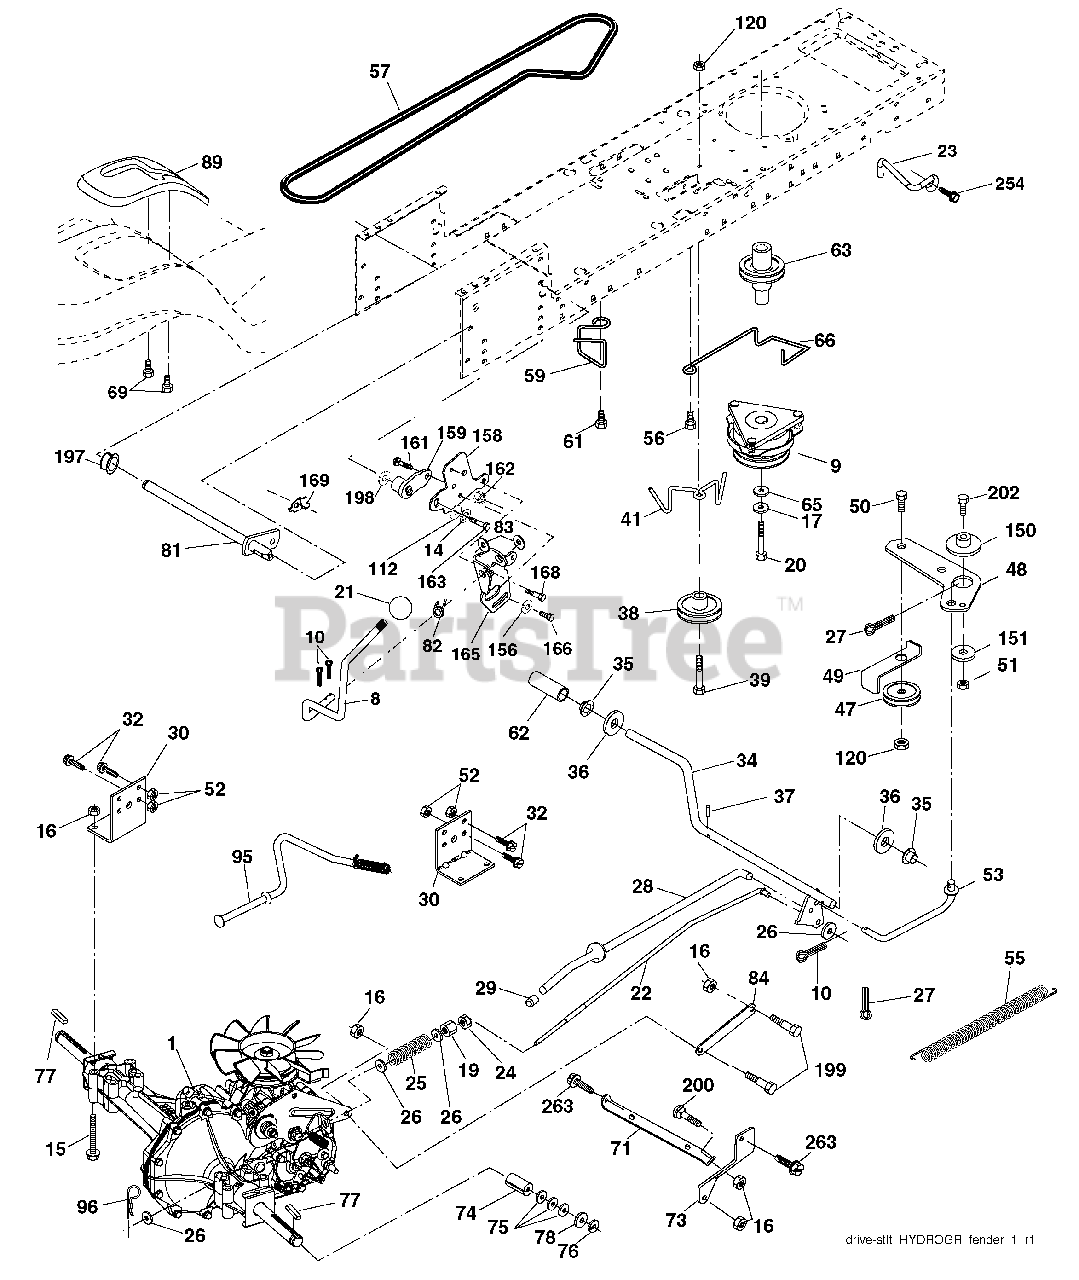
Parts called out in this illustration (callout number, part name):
8	Rod Shift
9	Clutch Ogura
10	Pin Cotter 1/8 x 1 CAD
14	Washer Lock Hvy Helical
15	Bolt, Hex FLGHD 5/16-18 Gr. 5
16	Nut Lock Hex W/Ins 5/16-18 unc
17	Washer
19	Nut Lock Hex W/Wsh 3/8-16 unc
21	Knob
22	Rod, Brake Hydro
23	Bracket Anti Rotation
24	Nut
25	Spring, Brake Rod
26	Washer
27	Pin Cotter 1/8 x 3/4 CAD.
28	Rod, Parking Brake
29	Cap, Parking Brake
30	Bracket, Transaxle
32	Bolt Hex Hd 5/16-18 unc x 3/4
34	Shaft, Foot Pedal
35	Bearing, Nylon
36	Washer
37	Pin, Roll
38	Pulley, Composite
39	Bolt Rdhd 3/8-16 unc x 2-3/4 Gr. 5
41	Keeper, Belt Idler
47	Pulley, Idler, V-Groove
48	Bellcrank Clutch Grnd Drv STL
49	Retainer, Belt
50	Bolt Carr Sh 3/8-16 x 1-1/2 Gr. 5
51	Nut Crownlock 3/8-16 unc
52	Nut Crownlock 5/16-18 unc
53	Link, Clutch
55	Spring, Return, Clutch
56	Screw 3/8-16 x 1-1/4
57	V-Belt, Ground Drive
59	Keeper, Center Span
61	Screw 3/8-16 x .875
62	Cover, Pedal
63	Pulley, Engine
64	Bolt Hex 7/16-20 x 4 x Gr. 5-1.5 Thr
65	Washer
66	Keeper Belt Engine
69	Screw Hex Wsh Hi-Lo 1/4 x 1/2 unc
71	Strap Torque Lh Hydro
73	Strap Torque Rh Hydro
74	Spacer, Axle
75	Washer 25/32 x 1-1/4 x 16 Ga.
76	E-Ring
77	Key, Square
78	Washer 25/32 x 1-5/8 x 16 Ga.
81	Shaft Asm. Cross Hydro
82	Spring Torsion T/A
83	Washer 17/32 x 3/4 x 16 Ga.
84	Link Transaxle
89	Console, Shift
95	Control Asm Bypass Hydro
96	Retainer Spring 1" Zinc/Cad
112	Washer 9/32 x 3/4 x 10 Ga.
120	Nut Lock Flg 3/8-16 unc
150	Spacer Retainer
151	Washer 13/32 x 2 x 10 Ga.
156	Washer Srrted 5/16 ID x 1.125
158	Bracket Shift Mount
159	Hub Shift
161	Bolt Rdhd Sqnk 1/4-20 x 3/4 Gr. 5
162	Nut Crownlock 1/4-20 unc
163	Bolt Hex Fin 1/4-20 unc x 1 Gr. 5
165	Bracket Pivot Lever
166	Screw 5/16-18 x 5/8
168	Bolt Shoulder 5/16-18 x .561
169	Plate Fastening Lt
197	Nyliner Snap-In 5/8" ID
198	Washer Nyl 7/8 ID x .105
199	Bolt Shoulder 5/16-18 unc
200	Bolt Rdhd Sqnk 5/16-18 unc x 1
202	Bolt Carr Sh 3/8-16 x 1-3/4 Gr. 5
254	Screw 3/8-16 x 1
263	Thdrol Screw 3/8-16 x 3/4
